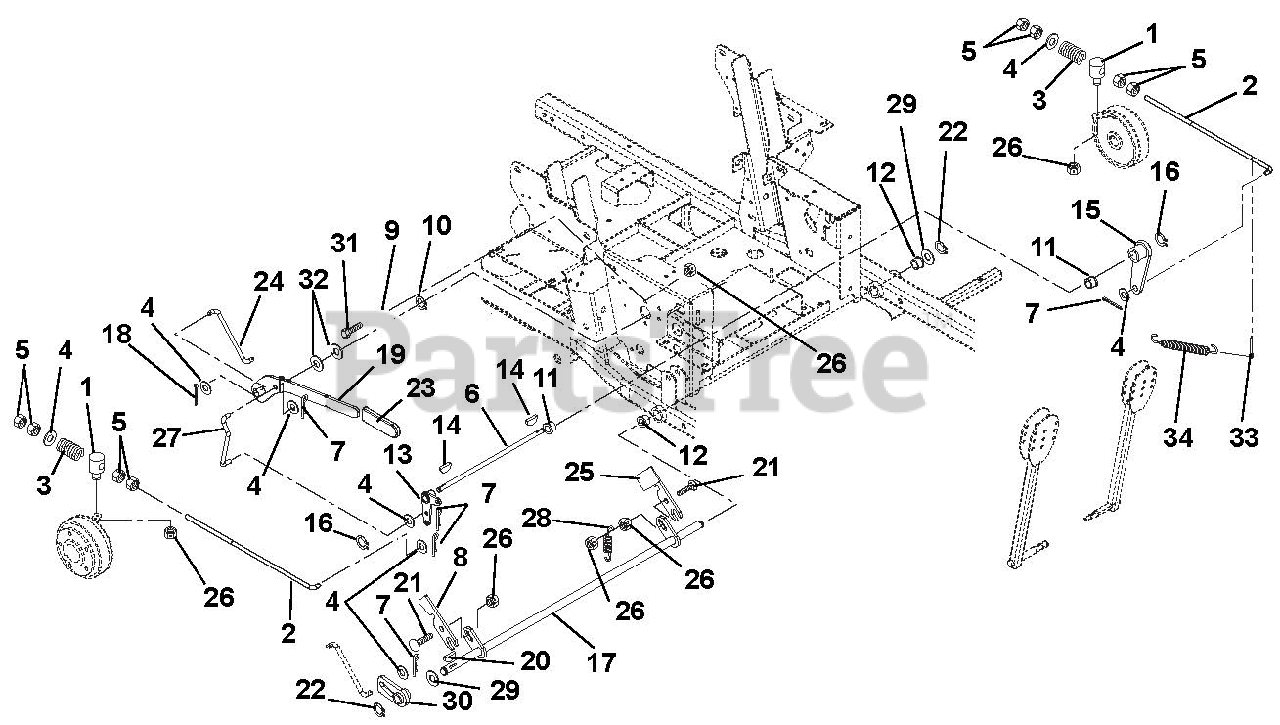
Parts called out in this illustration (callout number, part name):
1	Pivot, Brake Rod
2	Rod, Brake .38 x 19.00
3	Spring, Compression .142 x .710 x 1.75
4	Washer, Flat Steel .406 x .812 x .065
5	Nut, Hex .38-16
6	Shaft, Brake 2.00
7	Pin, Hair
8	Slide, Interlocking Brake
9	Bushing, Flange
10	Ring, Retaining External .625 x .05
11	Bushing, Flange Nylon .762 x 1.00 x .58 x 1.48
12	Bushing, Flange .515 x .75 x .745 x 1.00
13	Weldment, 200 Brake ACT. Arm
14	Key, Square .188X1.00X.188 SAE 8630
15	Arm, Brake Left Hand
16	Ring, Retaining External .625 x .050
17	Weldment, Mechanical Brake
18	Pin, Cotter External .09 x .75
19	Weldment, Brake Handle
20	Key, Woodruff .13 x .63
21	Bolt, Round Head Square Neck .31-18 x 1.25 Grade 5
22	Ring, Retaining External .50 x .05
23	Grip, Handle
24	Linkage, Brake Actuating
25	Interlock, Safety Switch
26	Nut, Locking Top Flange .31-18
27	Linkage, Brake Actuating
28	Spring, Tension .063 x .44 x 1.56
29	Washer, Flat Steel .505 x 1.00 x .062
30	Weldment, Parking Brake Hub
31	Bolt, Hex .31-18 x .75 Grade 5
32	Washer, Flat Steel .630 x 1.250 x .062
33	Pin, Cotter .12 x .75 Extended Prong Square Cut
34	Spring, Extension
